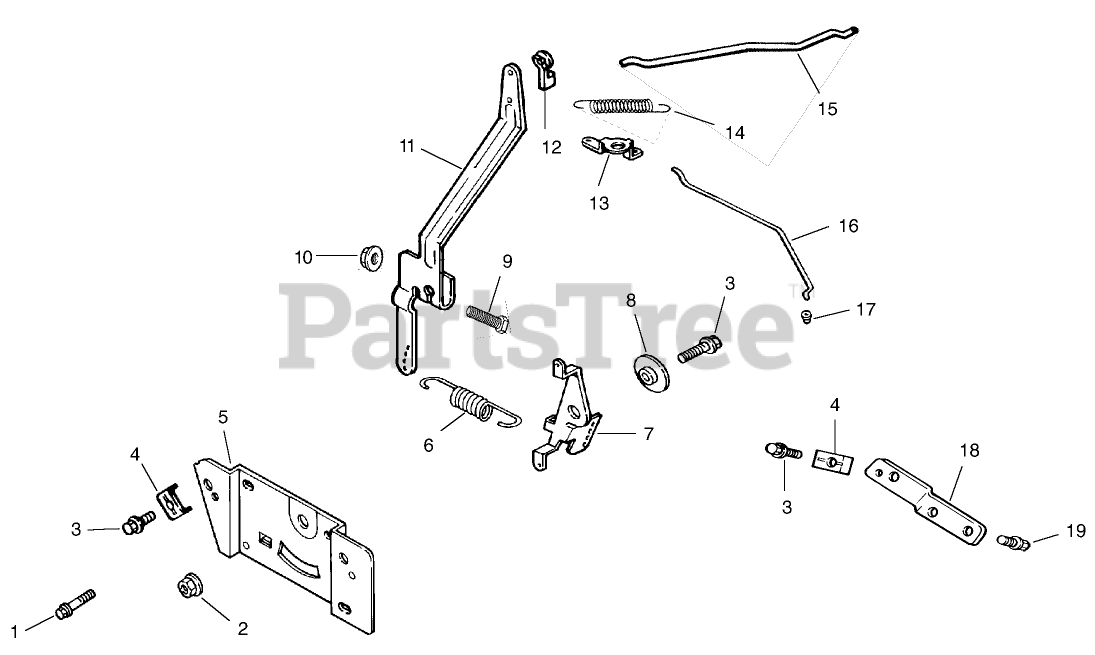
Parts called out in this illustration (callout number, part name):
1	Screw-Socket, 6 Lobed (Thread Forming, M6x1.0x20)
2	Nut-HF (M5x0.8)
3	SCREW-FLANGE, THREAD FORMING (M5X0.8X16)
4	CLAMP-CABLE
5	Plate-Control
6	Spring-Governor
7	Lever-Throttle, Inner
8	Spacer-Control ASM
9	Screw-Hex Flange, M6x1.0x25
10	NUT-FLANGE (M6X1.0)
11	Lever-Governor
12	BUSHING-RETAINING, LINKAGE
13	Lever-Choke, Upper
14	Spring-Linkage
15	Linkage-Throttle
16	Linkage-Choke, Upper
17	BUSHING-LINKAGE, THROTTLE
18	Bracket-Choke, Mount
19	SCREW-HHFTF (M5X.80X10)
